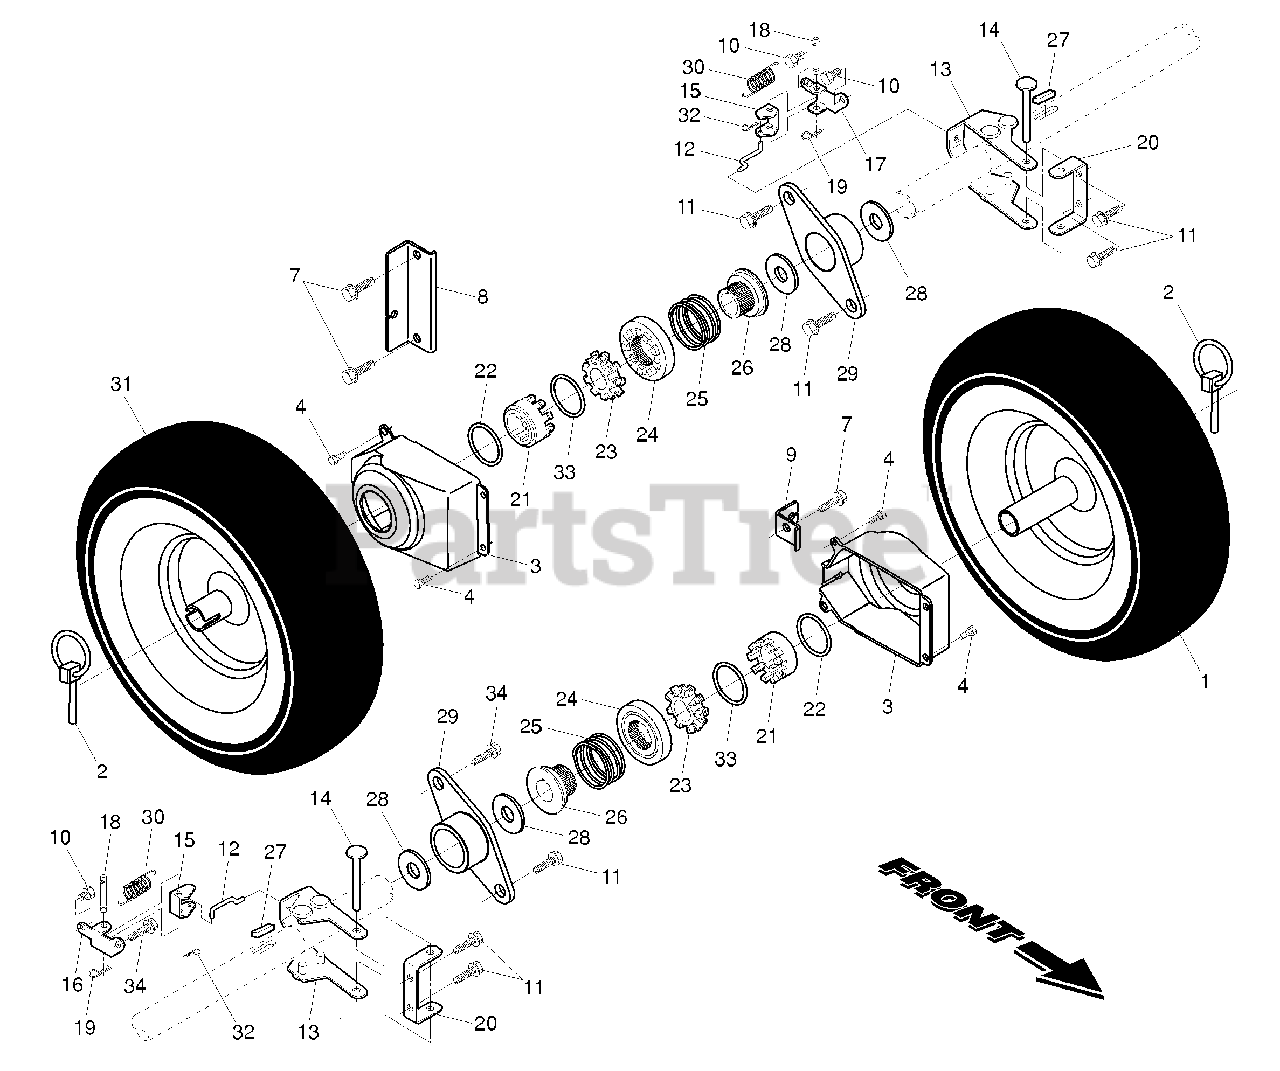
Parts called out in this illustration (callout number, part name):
1	Wheel Assembly, 16", Power Steering, LH
2	Pin, Klik 1/4
3	Cover, Power Steering
4	Bolt, Shoulder #10-24 x 5/8
7	Capscrew, Hex Head, Flanged 3/8-16x1
8	Bracket, SteeringCable, RH
9	Bracket, SteeringCable, LH
10	Screw, Hex Head 1/4-20 x 3/8
11	Screw, Hex Head 5/16-18 x 1/2
12	Link, Steering Yoke
13	Yoke, Steering
14	Pin, Steering Lever
15	Bellcrank
16	BracketAssembly, LH Steering
17	BracketAssembly, RH Steering
18	Pin, Steering Bellcrank
19	Retainer, Hairpin
20	Bracket, Steering
21	Driver, Wheel
22	Ring, Wire Retainer
23	Lobe, Wheel
24	Slide, Clutch
25	Spring, Clutch Slide
26	Lobe, Axle
27	Key, Square
28	Washer, Thrust 1"
29	Bearing, Axle
30	Spring, Return
31	Wheel Assembly, 16", Power Steering, RH
32	Clip, Retainer
33	Ring, Retaining
34	Screw, Hex Head 5/16-18 x 5/8
